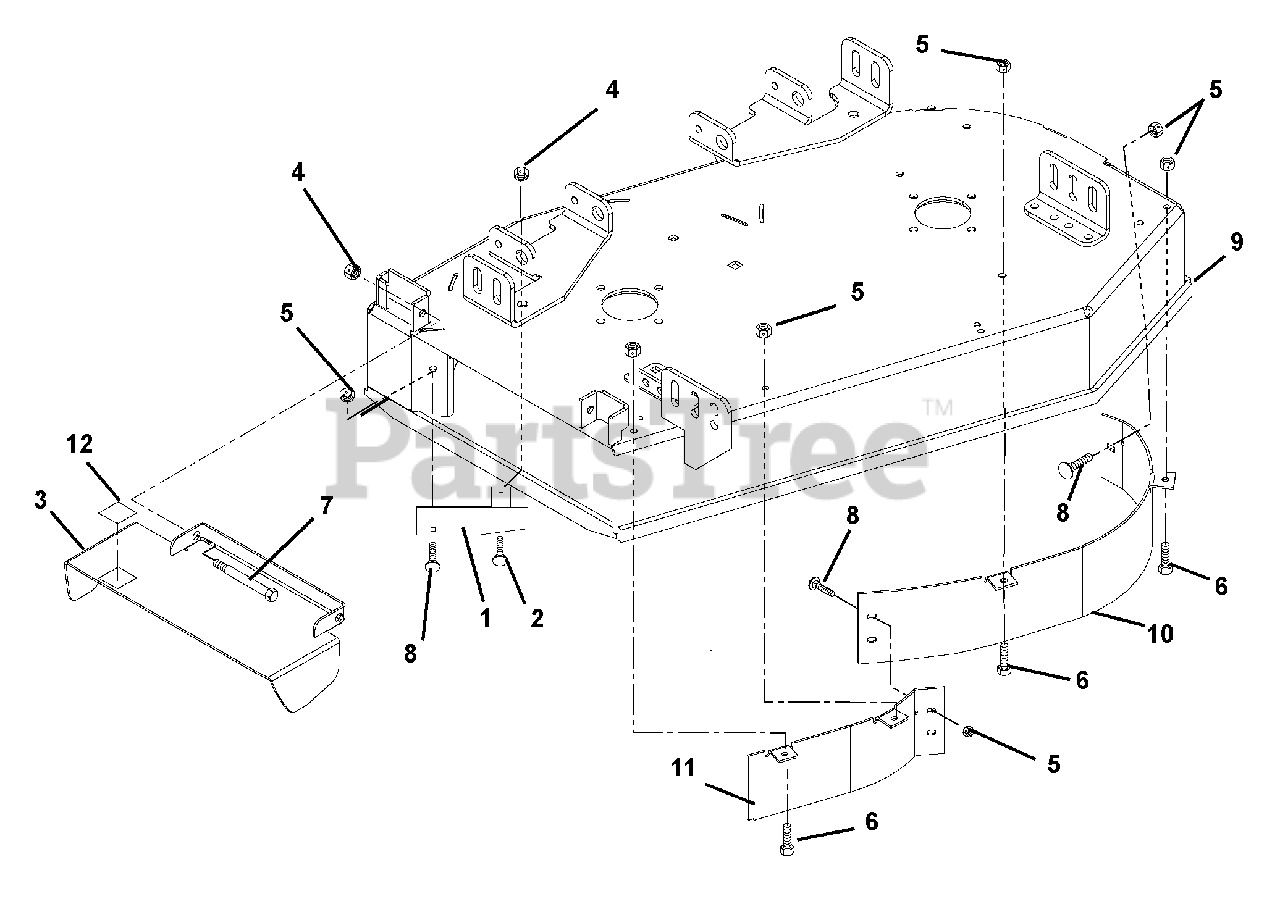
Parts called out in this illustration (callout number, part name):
1	Baffle, Deflector
2	Bolt-Round Head Square Neck .38-16 x 1.00 Grade 5
3	Chute, Discharge CE (314)
3	Chute, Discharge (056)
4	Nut, Nyloc Flange 3/8-16
5	Nut, Nyloc Flange 5/8-18
6	Bolt-Hex .31-18 x .75 Grade 5
7	Bolt-Shoulder .38-16 x .50 Socket Head
8	Bolt-Round Head Square Neck .31-18 x .75 Grade 5
9	Weldment, 34" Deck
10	Baffle, 34" Front Left Hand
11	Baffle, 34" Front Right Hand
12	Grip, Pedal 1.50 x 3.00
